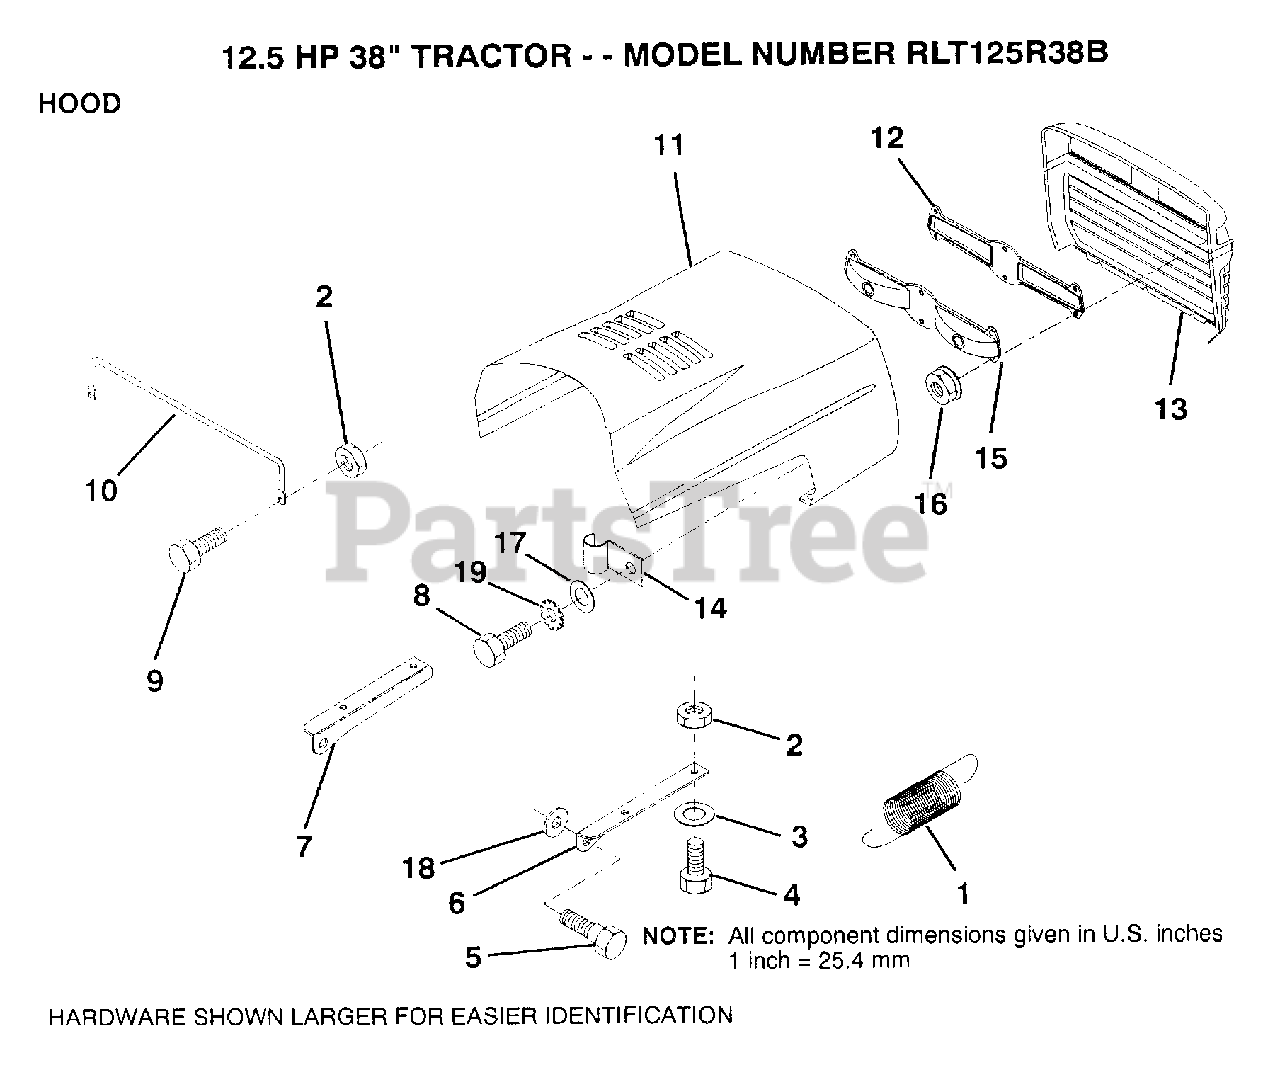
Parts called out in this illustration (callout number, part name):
1	EXT SPRING
2	NUT
3	WASHER
4	BOLT
6	BRKT HOOD RH
7	BRKT HOOD LH
10	"BRACE,HOOD"
11	HOOD
14	CLIP T
16	NUT
17	WASHER
18	WASHER
19	LOCKWASHER GT
